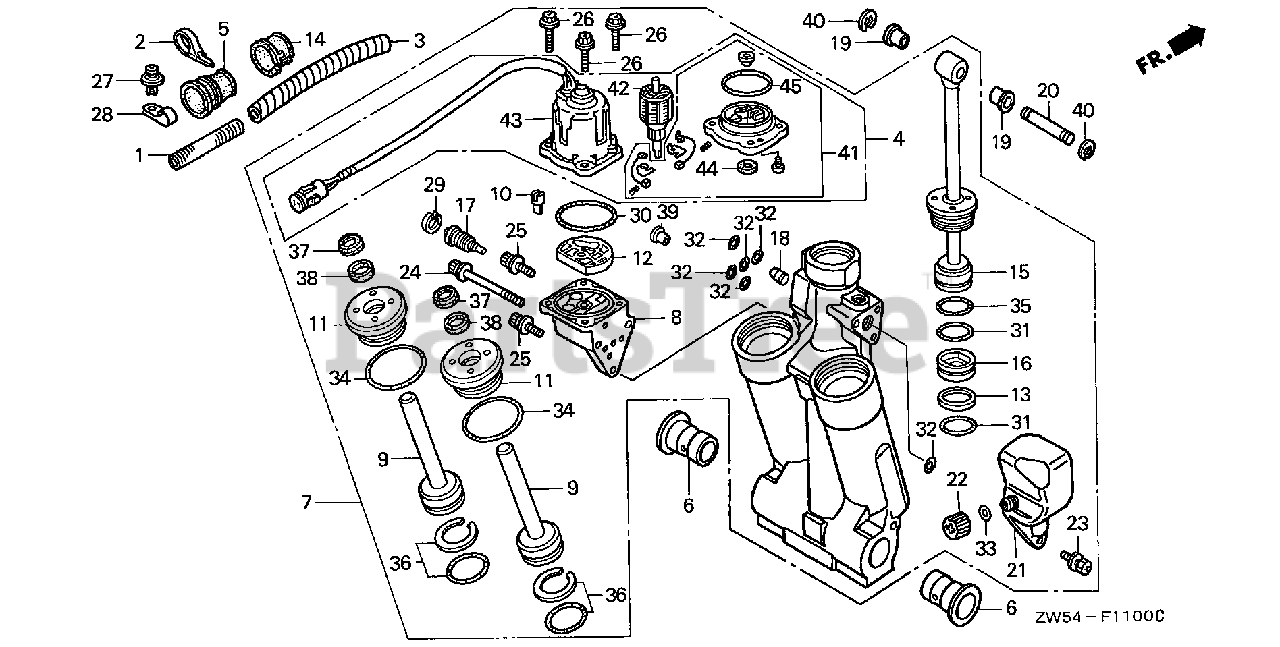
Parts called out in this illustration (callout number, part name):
1	TUBE, CORRUGATE (10MM)
2	BAND (BLACK 3.5X140)
3	TUBE, SPIRAL (12X14.6)
4	MOTOR ASSY., POWER TILT
5	GROMMET, CASE (LOWER) (C)
6	BUSH, SWIVEL CASE
7	TRIM-TILT ASSY., POWER *NH283* (STIN GRAY)
7	TRIM-TILT ASSY., POWER
8	PUMP ASSY.
9	ROD, PISTON (B)
10	JOINT, DRIVE
11	GUIDE, ROD
13	RING, BACK-UP
14	BUSH, MOTOR CODE
15	ROD, PISTON
16	PISTON, FREE
17	VALVE, MANUAL
18	VALVE, RESERVOIR
19	BUSH, CYLINDER (LOWER)
20	PIN, CYLINDER (UPPER)
21	TANK, OIL
22	CAP, OIL TANK
23	BOLT, RECESSED
24	BOLT A, SOCKET
25	BOLT B, SOCKET
26	BOLT, HEX.
27	SCREW, RIVET (5X10)
28	CLIP (10.7MM)
29	CIRCLIP (INNER)
32	O-RING
33	O-RING
36	O-RING SET
37	SEAL, WATER
39	COLLAR, ORIFICE
40	E-RING (15MM)
41	BRACKET ASSY.
42	ARMATURE
43	YOKE ASSY.
45	O-RING
